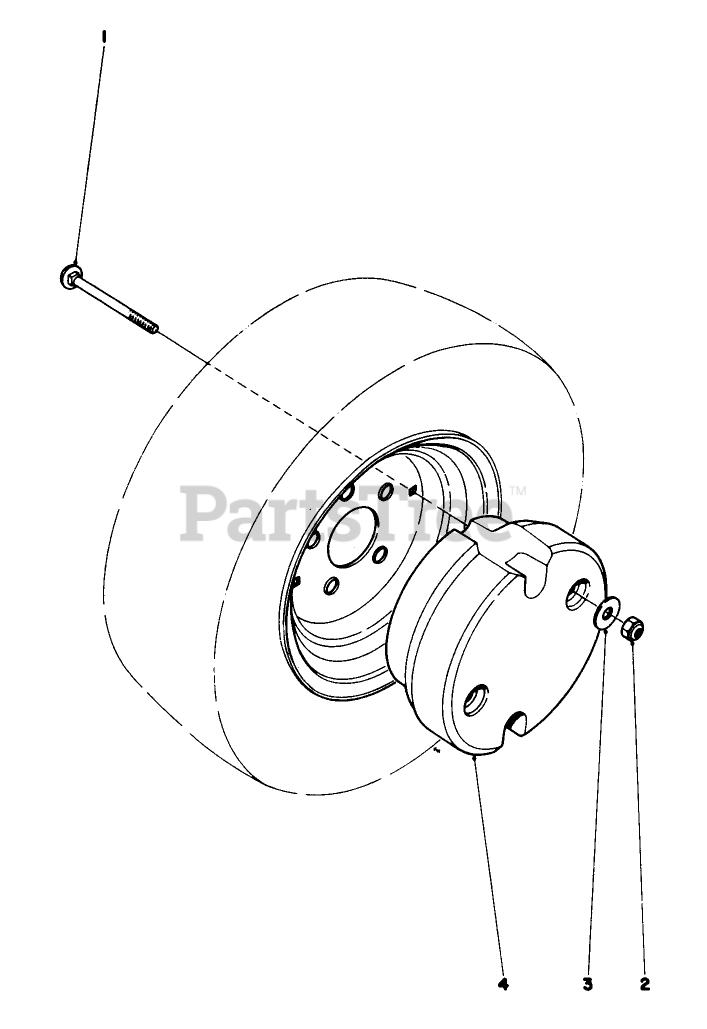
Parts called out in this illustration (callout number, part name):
1	SCREW-CARR
2	NUT-LOCK, NI
3	WASHER-FLAT
4	Wheel Weight
